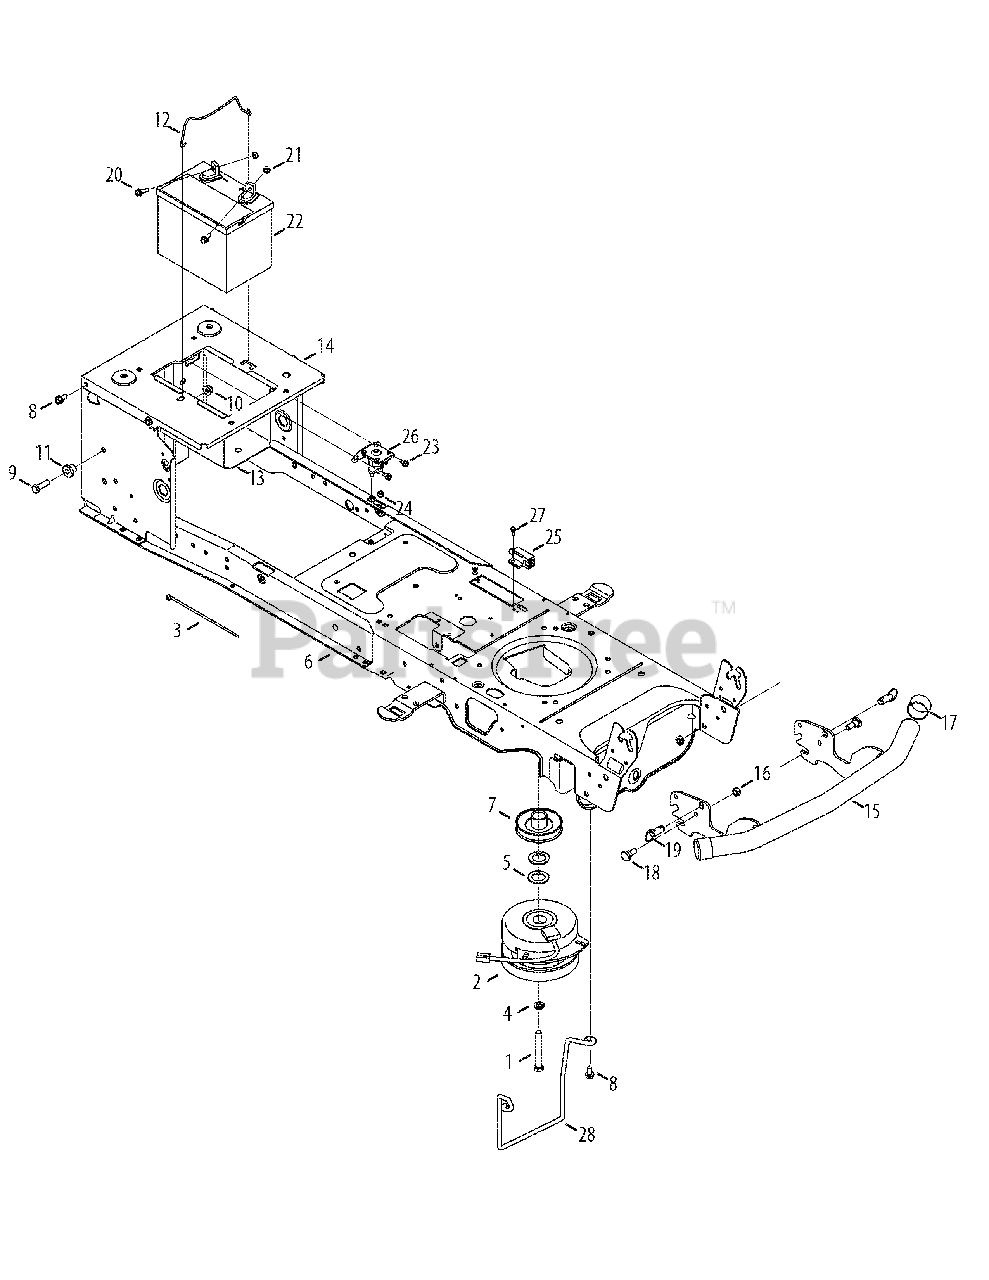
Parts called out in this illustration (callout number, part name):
1	Hex Head Screw, 7/16-20:3.50
2	Electric PTO Clutch
3	Cable Tie, 3/16 x .05 x 7.4
4	Lock Washer, 7/16
5	Flat Washer, 1.031 x 1.620 x .095
6	Frame
7	Electric PTO Engine Pulley
8	Taptite Screw, 5/16-18:.750
9	Hex Head Screw, 3/8-16:1.25
10	Flangelock Nut, 3/8-16
11	Shoulder Spacer, .38 x 1.0 x .70
12	Battery Holder Rod
13	Battery Tray
14	Seat Frame Bracket
16	Hexlock Nut, 3/8-16
17	Bumper Cap
18	Shoulder Bolt, .496 x .336
19	Quick Release Pin
20	Hex Head Flange, 1/4-20:.75
21	Sems Nut, 1/4-20
22	Battery
23	Taptite Screw, 1/4-20:0.375
24	Flangelock Nut, 1/4-20
25	Interlock Switch
26	Solenoid, 12 V
27	Shoulder Screw, #10-32:.500
28	Belt Keeper Rod
